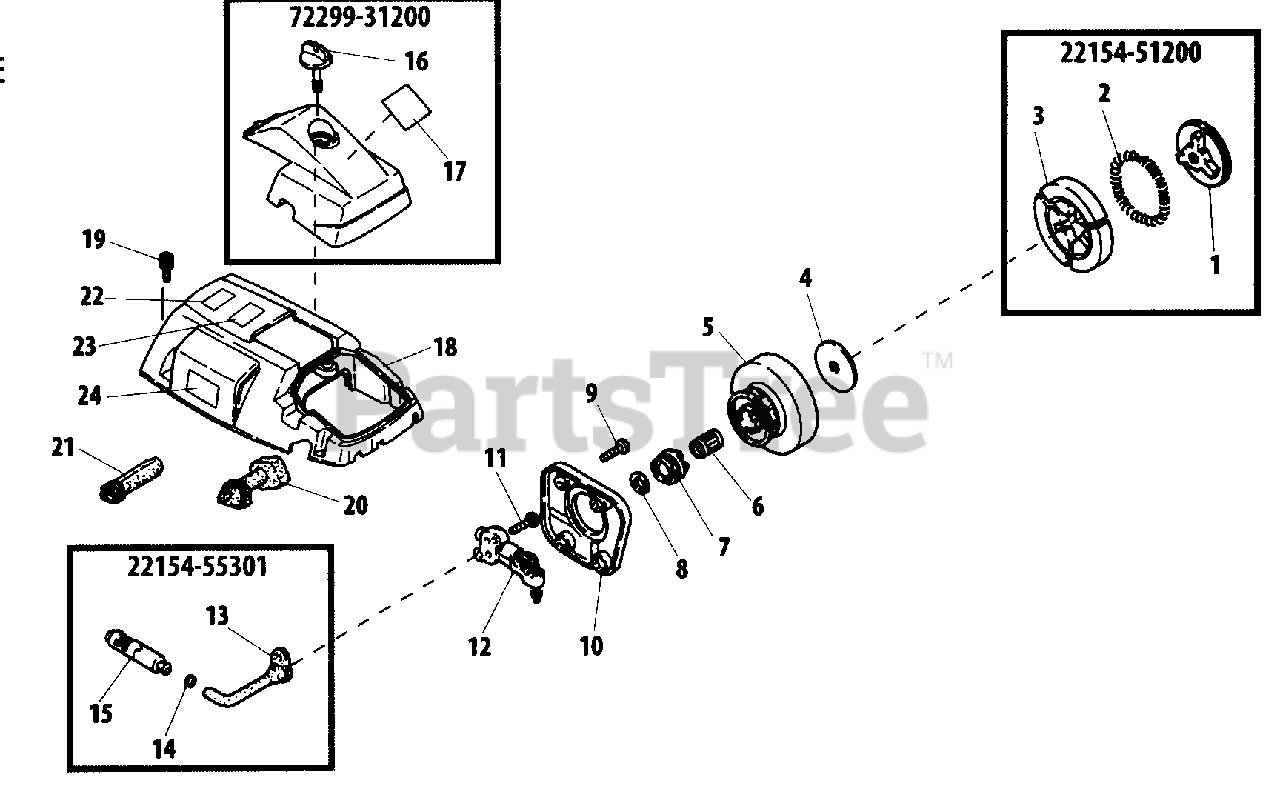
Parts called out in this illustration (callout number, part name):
1	BOSS, CLUTCH
2	SPRING, CLUTCH
3	SHOE, CLUTCH
4	WASHER, CLUTCH
5	DRUM, CLUTCH
6	BEARING, NEEDLE
7	GEAR
8	PLATE, THRUST
9	SCREW, ADHESIVE M4×12
10	COVER, PUMP
11	SCREW, ADHESIVE M4×12
12	OIL PUMP ASSY
13	PIPE, OIL
14	CLIP
15	FILTER, OIL
16	THUMBSCREW
17	LABEL, CAUTION K
18	COVER, ENGINE
19	BOLT, ADHESIVE M4×16
20	GROMMET
21	GROMMET
22	LABEL - CAUTION
23	LABEL, CAUTION
24	LABEL, CAUTION A
22154-51200	CLUTCH ASSY
22154-55301	PIPE ASSY, OIL
72299-31200	AIR FILTER COVER ASSY
